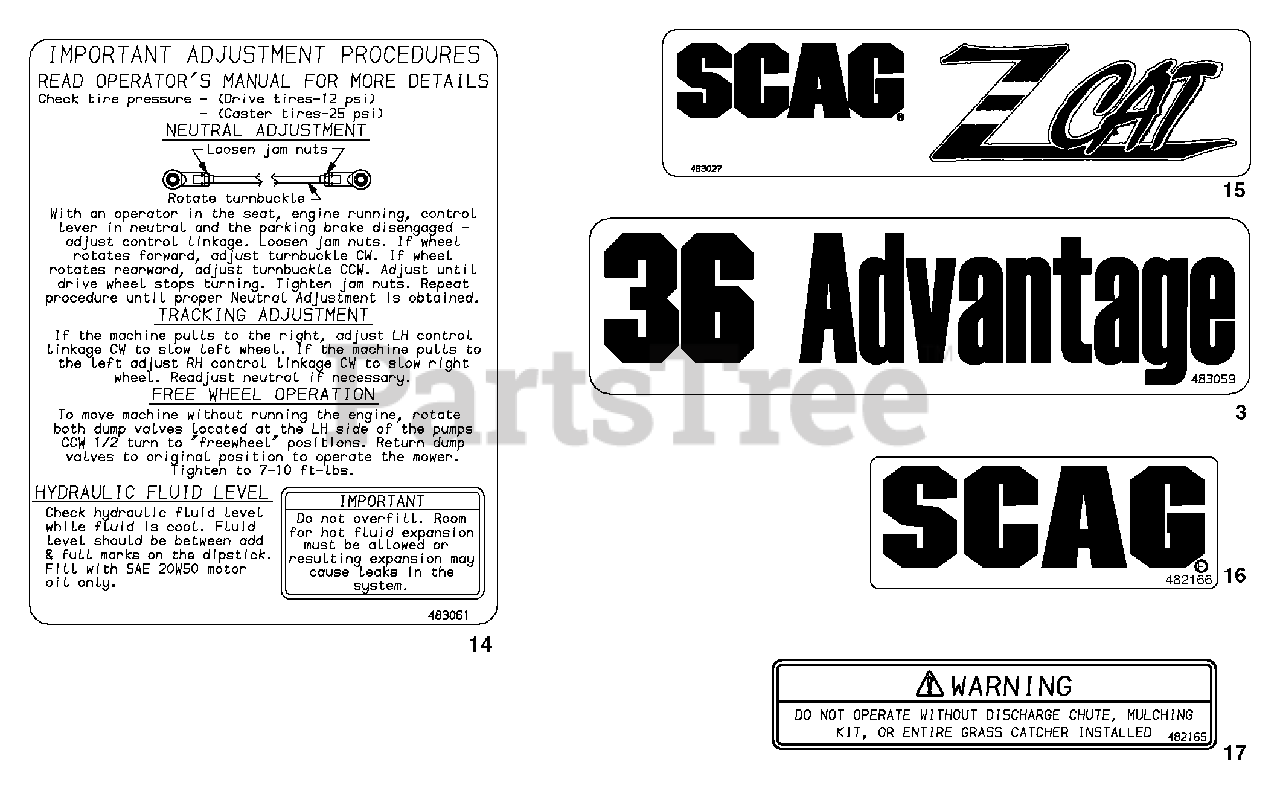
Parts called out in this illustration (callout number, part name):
3	Decal, 36 Advantage 483060
14	Decal, Seat Support
15	Decal, Rear SZC
16	Decal, Front Footplate
17	Decal, Discharge Chute
